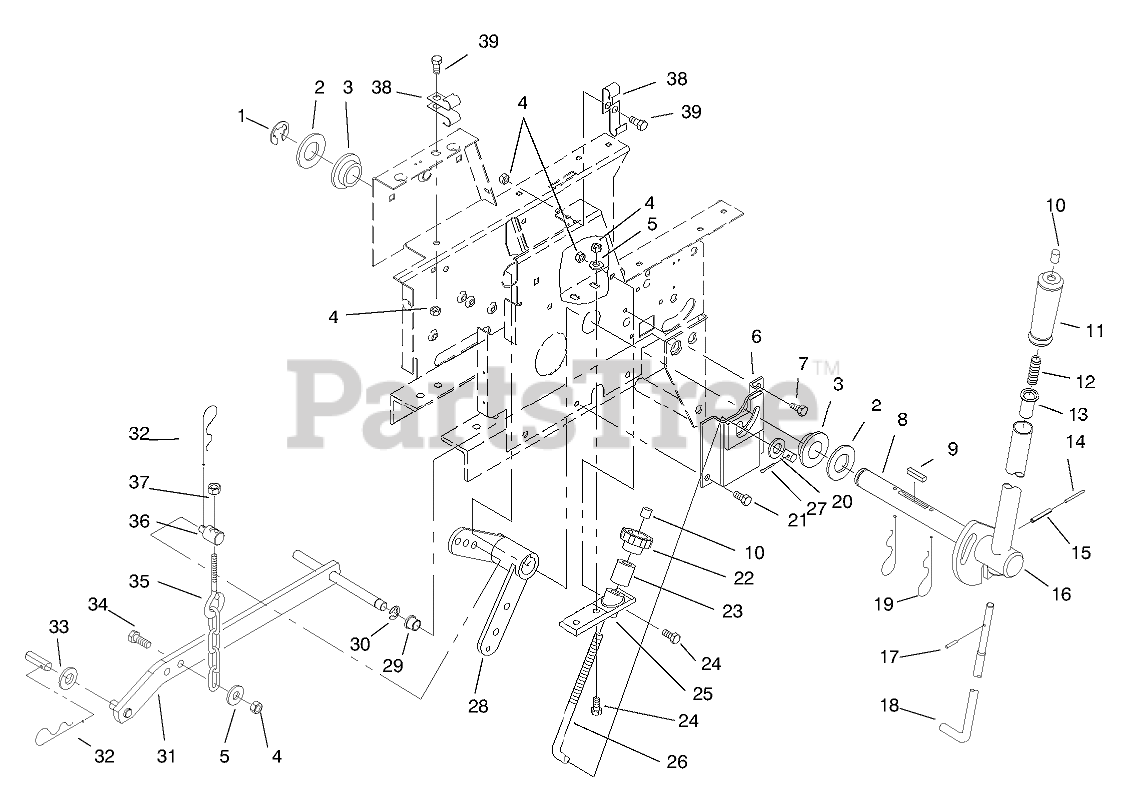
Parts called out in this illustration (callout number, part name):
1	RING-RETAINING
2	WASHER-FLAT
3	BEARING-FLANGE
4	NUT-LOCK, NI
5	WASHER-PLAIN
6	LIFT LEVER ASM
7	Bolt
8	SHAFT-LIFT LEVER
9	KEY-SQUARE
10	CAP-ROD, PLUNGER
11	GRIP-HANDLE
12	SPRING-COMPRESSION
13	RETAINER-SPRING
14	PIN-SPRING
15	PIN-ROLL
16	LIFT HANDLE ASM
17	PIN-SPIROL
18	ROD-LATCH LIFT
19	PIN-HAIR
20	WASHER-FLAT
21	SCREW-SELF TAP
22	KNOB-LIFT CONTROL
23	SLEV-LIFT ADJS
24	SCREW-HH
25	CASTING-LIFT LEVER
26	ROD-HEIGHT CONTROL
27	PIN-COTTER
28	LIFT LEVER ASM
29	BUSHING
30	RING-RETAINING, EXTERNAL
31	LIFT BAR ASM
32	PIN-HAIR
33	WASHER-FLAT
34	SCREW-HH
35	CHAIN-LIFT
36	TRUNNION-LIFT
37	NUT-LOCK, NI
38	CLIP
39	SCREW-HH
